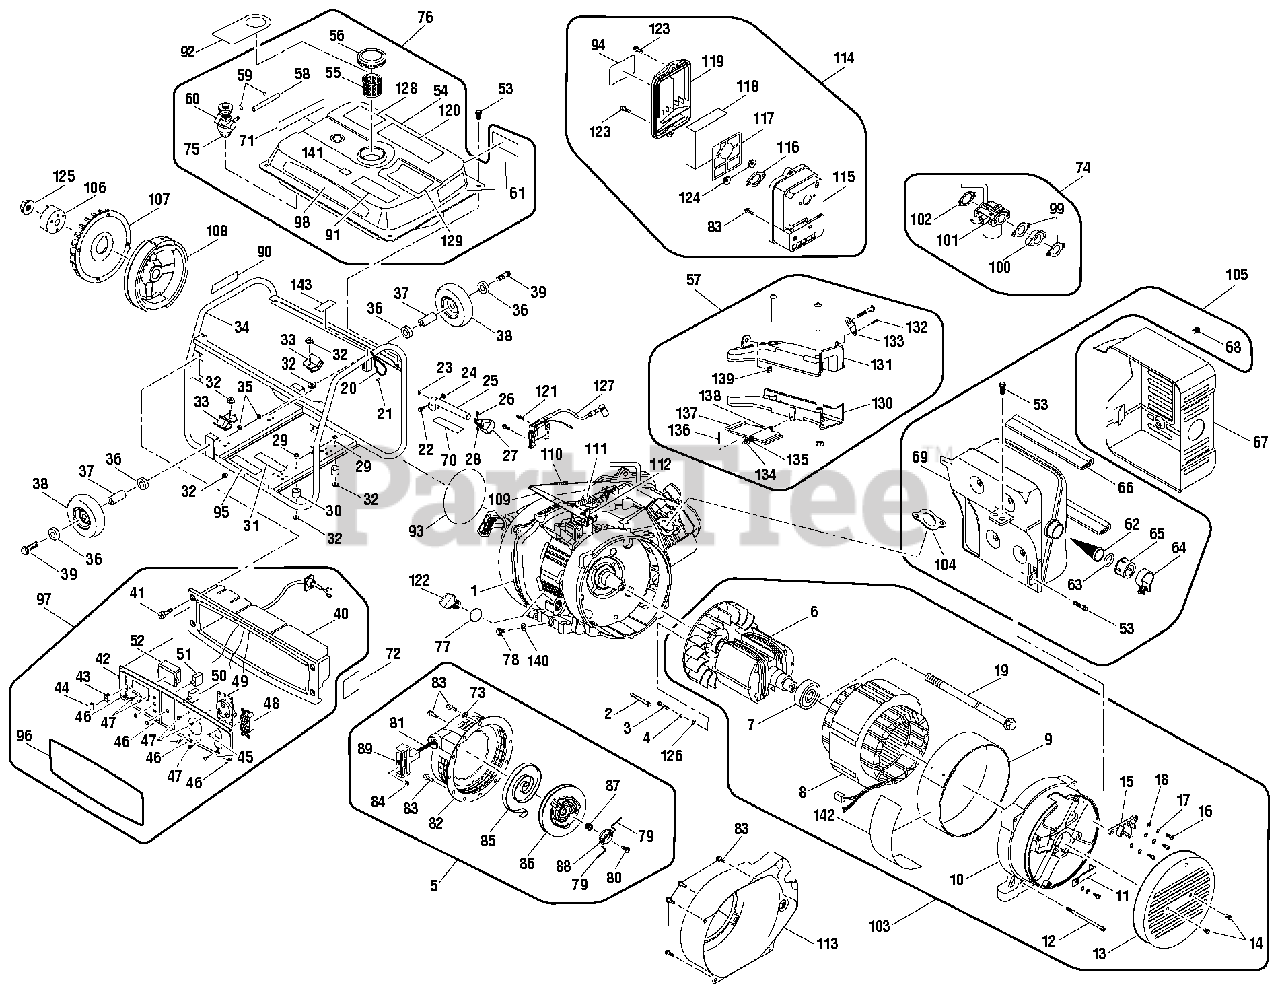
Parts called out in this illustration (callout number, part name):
1	Engine SPE195
2	Bolt (M8 x 35 mm)
3	Bolt (M6 x 12 mm)
5	Recoil Stator Assembly
6	Rotor Assembly
8	Stator Assembly
9	Stator Cover
10	Rear Frame
11	Wire Compressing Plate
12	Bolt (M6 x 103 mm) (88)
13	Rear End Cover
14	Bolt (M6 x 10 mm)
15	Wire Rack
16	Screw (M5 x 14 mm)
17	Lock Washer (M5)
18	Washer (M5)
22	Bolt (M8 x 40 mm)
23	Handle Stem Head
24	Lock Nut (M8)
26	Square Bolt
29	Screw (M8 x 40 mm)
30	Alternator Vibration Absorber
31	Combustion Warning Label
33	Engine Vibration Absorber
35	Lock Nut (M10 x 1.25 in.)
36	Wheel Bushing
37	Axis Cover
39	Bolt (M10 x 75 mm)
40	Control Box
41	Screw (M6 x 14 mm)
42	Control Panel
43	Engine Switch
44	Switch Jacket
45	Bolt (M3.5 x 9 mm)
46	Bolt (M3.9 x 9 mm)
47	Bolt (M4 x 8 mm)
48	120 V 20 Amp Receptacle
49	120 V 30 Amp Receptacle
50	AC Circuit Breaker (20 A)
51	AC Circuit Breaker (25 A)
52	4 in 1 Digital Meter
53	Bolt (M6 x 12 mm, Fillister Hd.)
54	Fuel Tank
55	Fuel Strainer
56	Fuel Tank Cap
57	Air Conduct Assembly
58	Fuel Hose
59	Fuel Hose Clip
60	Fuel Cock
61	Hot Surface Label
62	Muffler Screen
65	Muffler Screen Cover
66	Shockproof Bar
67	Muffler Cover
68	Bolt (M6 x 10 mm)
70	Locking Pin Label
71	Start Guide Label
72	Ground Label
73	Bushing Block
74	Carburetor Assembly
76	Fuel Tank Assembly
77	Oil Filler Seal
78	Drain Plug (M10 x 1.25-16 )
82	Starter Case
83	Screw (M6 x 12 mm)
84	Rope Clip
85	Starter Spring
86	Drum Sheave
88	Pawl Guide
89	Starter Handle
90	Fire Danger Label
91	Ground Warning Label
92	Oil Hangtag
93	Engine Shround Logo
94	Choke Label
95	Lubricant Label
96	Control Panel Label
97	Control Panel Assembly
98	Logo Label
101	Carburetor
103	Alternator Assembly
104	Exhaust Gasket
105	Muffler Assembly
106	Starting Hub
109	Governor Arm
111	Carburetor Spring
114	Air Cleaner Assembly
115	Air Filter Case
117	Element Fitting Plate
118	Air Filter Element
119	Air Filter Cover
120	Warning Label
121	Screw (M6 x 20 mm)
122	Oil Cap/Dipstick
123	Screw (M6 x 12 mm, Fillister Hd.)
125	Nut (M16, Flange Hd.)
127	Ignition Module
128	CPSC Label
129	Danger Label (FR)
130	Warm Air Tube Hypotheca
131	Warm Air Tube Epitheca
132	Bolt (M4.8 x 16 mm)
133	Connector
136	Cotter Pin
137	Valve Plate
139	Elastic Nut (M44.8)
140	Drain Plug Gasket
141	E85 Label
142	Data Label
143	EMC Label
